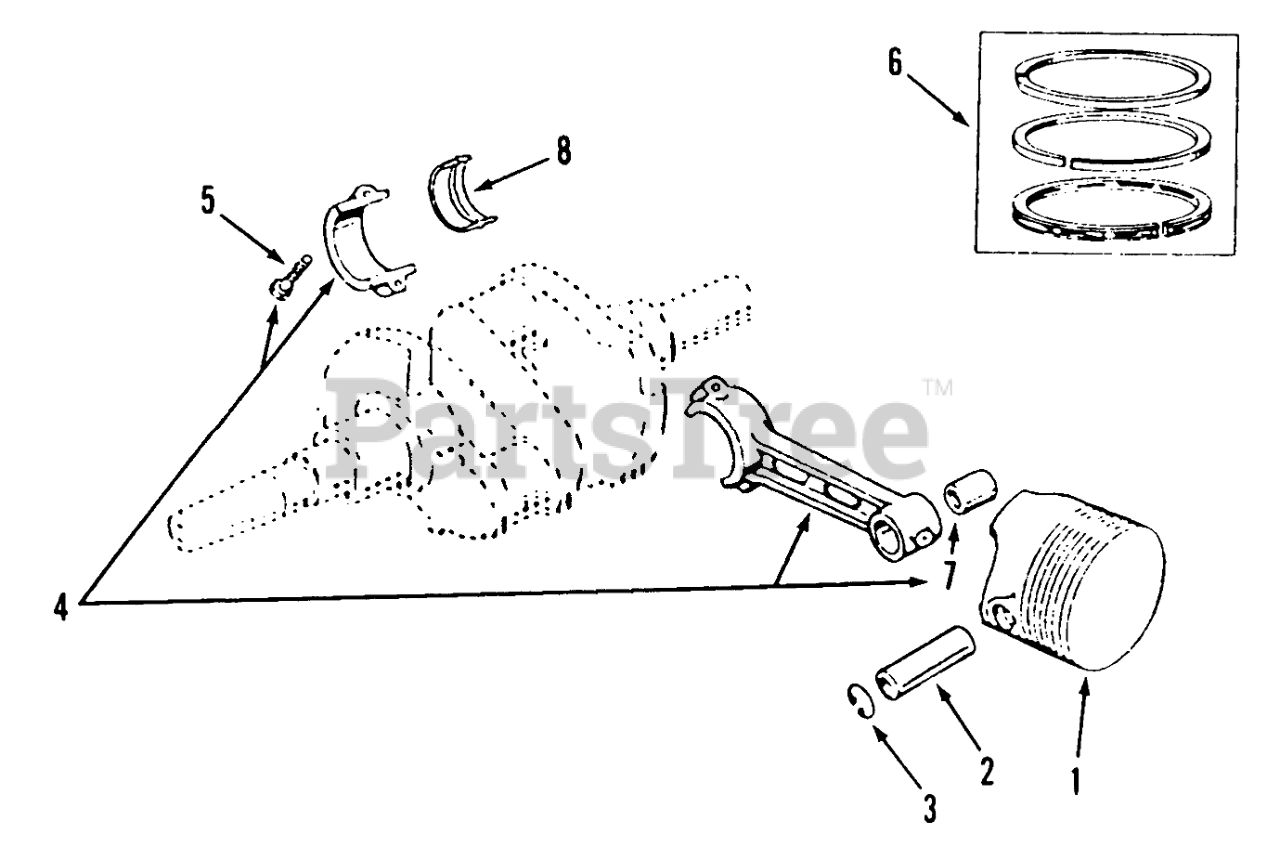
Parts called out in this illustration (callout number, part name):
1	Piston & Pin (Incl. Pin & Retaining Ring)
2	PIN-PISTON
3	RETAINING RING
4	Rod-Connecting (Incl. Bolts)
5	BOLT-PLACE
6	Set-Piston Ring
7	BUSHING-PISTON PIN
8	Bearing-Connecting Rod, Half
